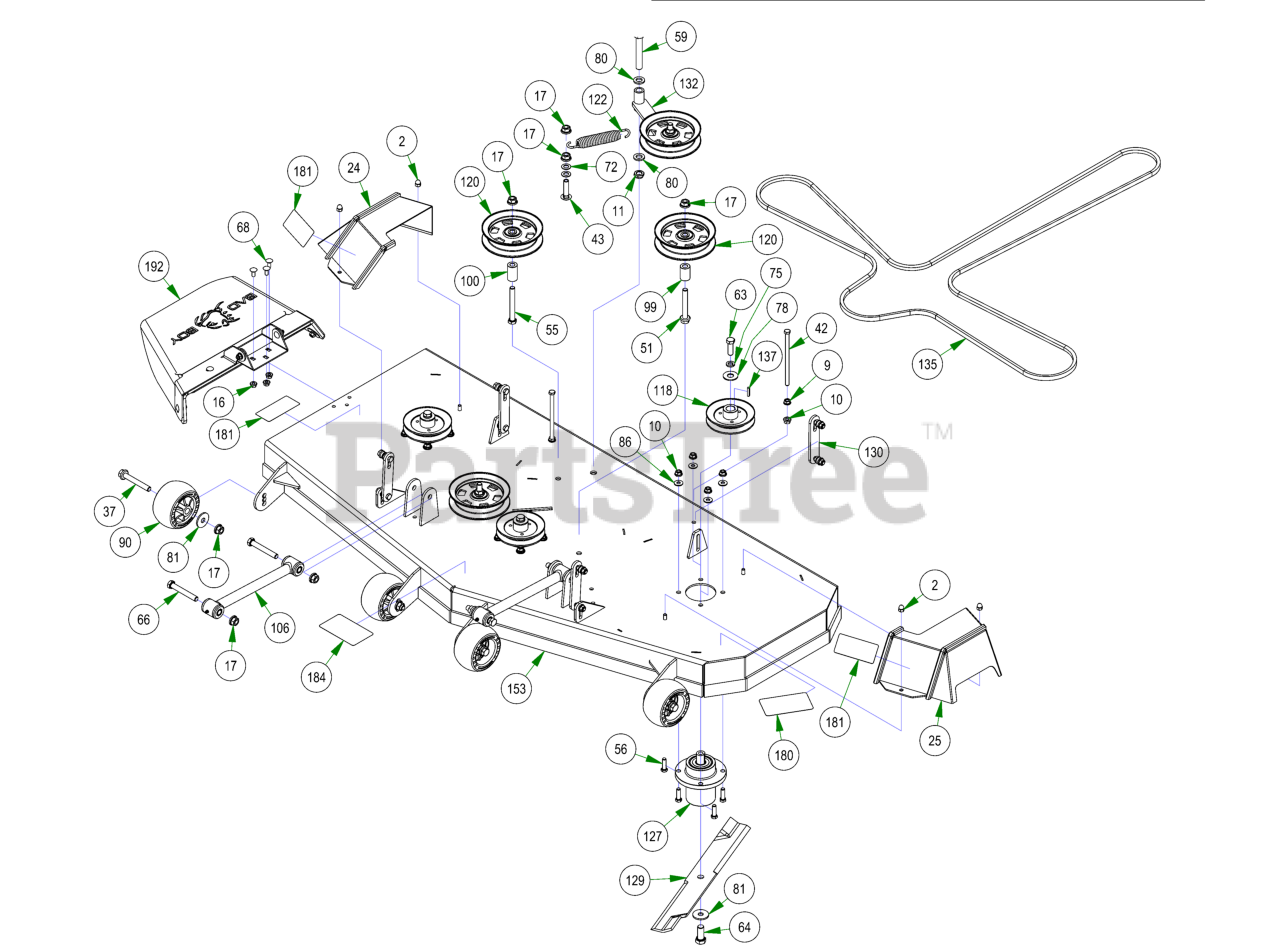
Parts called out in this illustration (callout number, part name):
2	5/16-18 ACORN NUT HIGH-CROWN ZC
9	3/8-16 HEX SERRATED FLANGE NUT HARD/ZINC
10	3/8-16 NYLON INSERT FLANGE LOCKNUT (GR.F) ZINC
11	5/8-11 NYLON INSERT JAM LOCKNUT ZINC
16	5/16-18 NYLON INSERT FLANGE LOCKNUT ZINC
17	1/2-13 NYLON INSERT FLANGE LOCKNUT ZINC
24	2021 Maverick 54”/60” RH Pulley Cover
25	2021 Maverick 54”/60” LH Pulley Cover
37	1/2-13 X 90MM HEX FLANGE BOLT W/SHOULDER (GR.8) ZINC
42	3/8-16 X 6.5 HEX CAP SCREW (GR.5) ZINC
43	1/2-13 X 2 CARRIAGE BOLT ZINC
51	1/2-13 X 3-1/2 HEX FLANGE BOLT (GR.8) ZINC
55	1/2-13 X 4 HEX CAP SCREW (GR.8) ZINC YELLOW
56	3/8-16 X 1-1/4 HEX CAP SCREW (GR.5) ZINC
59	5/8-11 X 4 HEX CAP SCREW (GR.8) ZINC YELLOW
63	1/2-20 X 1-1/2 HEX CAP SCREW (GR.5) ZINC
64	5/8-18 X 1-1/2 HEX CAP SCREW (GR.8) ZINC YELLOW
66	1/2-13 X 3-1/2 HEX CAP SCREW (GR.5) ZINC
68	5/16-18 x 3/4 Carriage Bolt
72	.517 SQ WDTH ID X .937 OD X .060 THICK F/W PHOS/OIL
75	1/2 SPLIT LOCKWASHER (GR.8) ZINC/YELLOW
78	5/8 USS FLAT WASHER (1-3/4" OD) GR.8 ZINC YELLOW
80	.635 ID X 1.120 OD X .140 THICK FLAT WASHER NYLON
81	1/2 BELLEVILLE WASHER (1-5/8 OD X .140 THK) ZINC
86	5/16 USS FLAT WASHER (7/8 OD) ZINC
90	Deck Wheel
99	.502 ID X .750 OD X 1.500 Long Spacer
100	1 3/4" Pulley Spacer
106	Hybrid Turnbuckle/Deck Locator
118	60" MZ Deck Pulley (Representation Only)
120	5-3/4 Idler Pulley
122	Deck Idler Spring
127	Spindle Assembly-MZ
129	60" High Lift Fusion Blade
130	Deck Hanger Assembly
132	2017 MZ/ZT Deck Idler Assembly
137	3/16 X 1 SQ MACHINERY KEY 1018 STL ZINC
153	60" MZ Deck Welment-Painted
180	2018 60" Deck Decal
181	Danger Decal-Spindle/Discharge
184	Deck Belt Route Decal
192	MZ Discharge Chute Assembly
